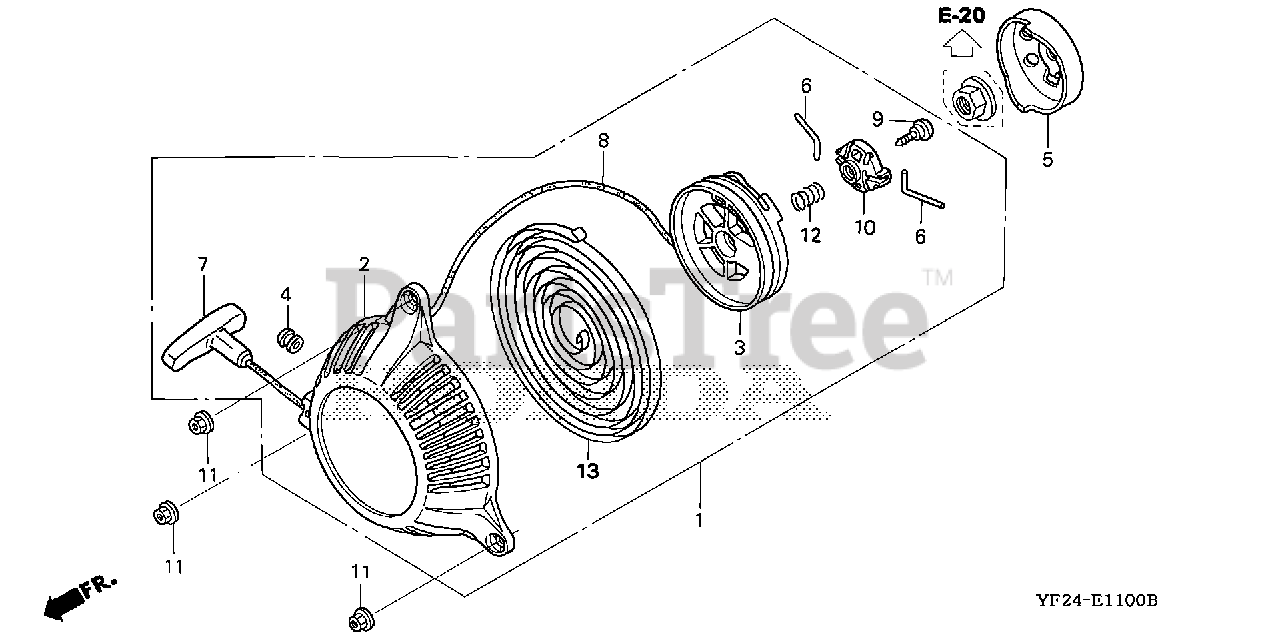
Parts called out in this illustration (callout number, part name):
1	STARTER ASSY., RECOIL
2	CASE, RECOIL STARTER
3	REEL, RECOIL STARTER
4	GUIDE, ROPE
5	PULLEY, RECOIL STARTER
7	KNOB, RECOIL STARTER
8	ROPE, RECOIL STARTER
9	SCREW, SETTING
11	NUT, FLANGE (5MM)
12	SPRING, FRICTION
13	SPRING, RECOIL STARTER
